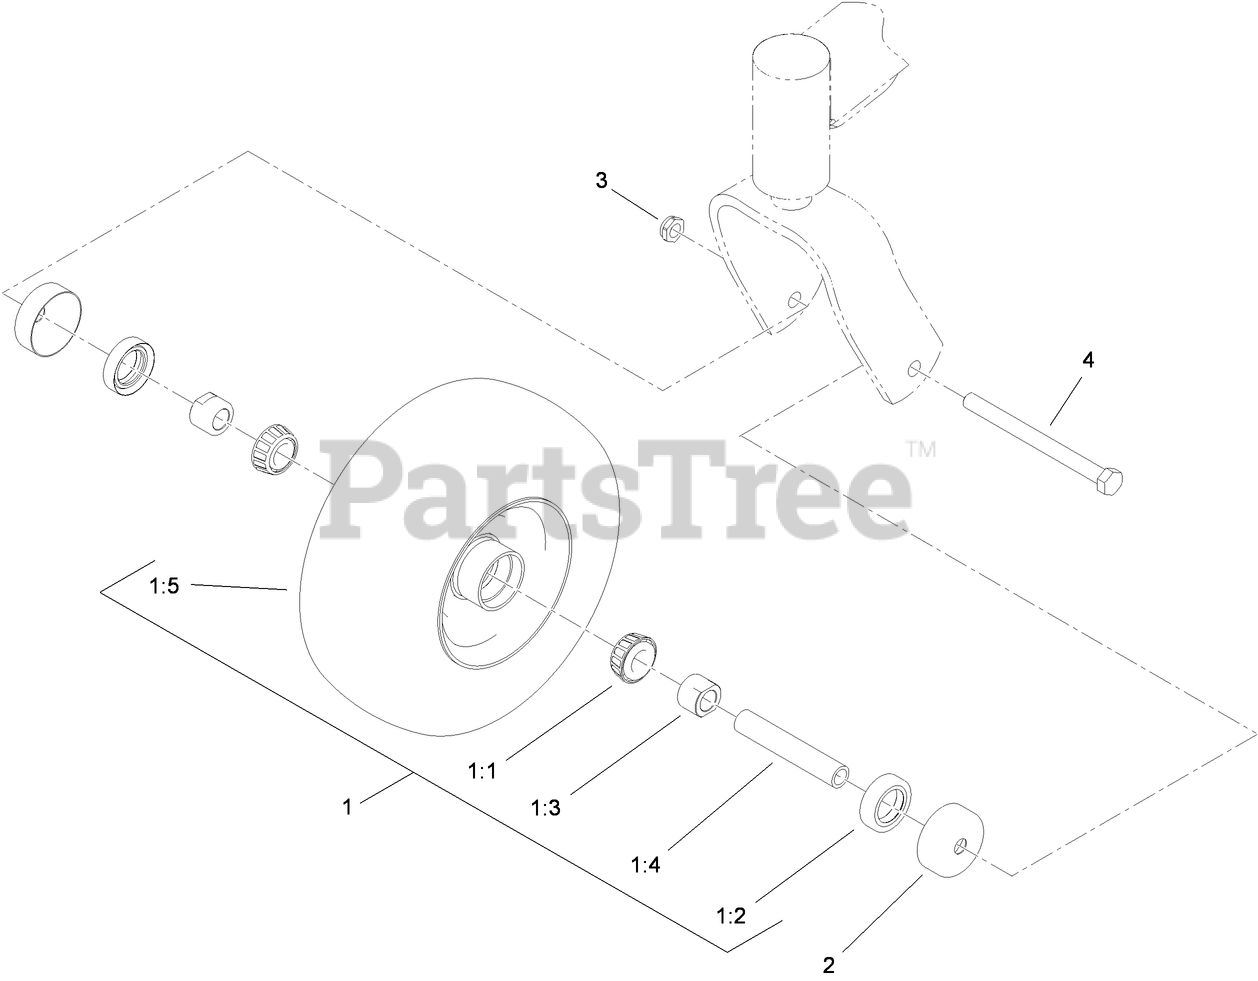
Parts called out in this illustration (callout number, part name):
1	WHEEL AND BEARING ASM
1:1	BEARING-CONE, TAPER
1:2	SEAL-CASTER
1:3	SPACER-NUT
1:4	AXLE-CASTER
1:5	WHEEL AND TIRE ASM
2	GUARD-SEAL
3	NUT-LOCK, NI
4	SCREW-HH
